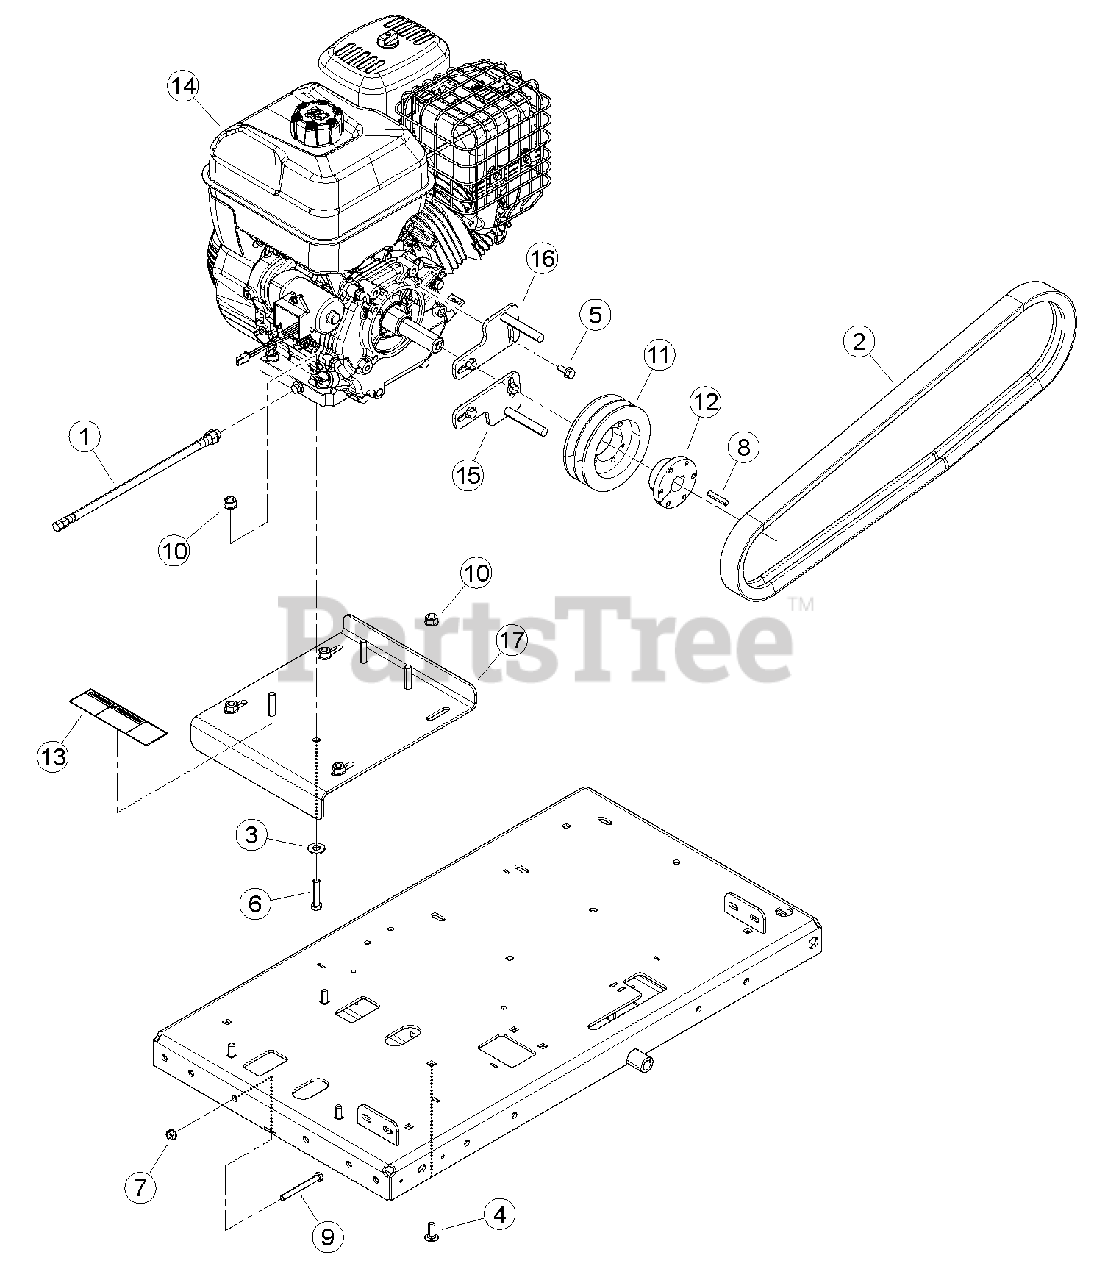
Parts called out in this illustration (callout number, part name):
1	BELT, 2RB61 ARAMID
2	HOSE ASSEMBLY, CRANKCASE DRAIN
3	WASHER, 3/8 FLAT
4	BOLT, 3/8-16 X 1 GR5 CRG
5	BOLT, 5/16 X 3/4 SERRATED FLANGE NF
6	BOLT, 3/8 X 1-3/4 GR5 HCS ZP
7	NUT, 5/16-18 SERRATED FLANGE NC
8	KEY, 1/4 SQ X 1-1/2 LG PLAIN
9	BOLT, 5/16 NC X 3 FULL THD
10	NUT, 3/8-16 NYLOCK FLANGE
11	SHEAVE, 2B5.2 SDS
12	BUSHING, SDS 1"
13	DECAL, CHECK WHEELS
14	ENGINE, 420CC 2100 SERIES B&S (FOR SERVICE SEE ENGINE OWNER'S MANUAL OR NEAREST AUTHORIZED BRIGGS & STRATTON INDUSTRIAL ENGINE DEALER)
15	WELDMENT, BELT GUIDE BOTTOM
16	WELDMENT, BELT GUIDE TOP
17	PLATE, ENGINE
